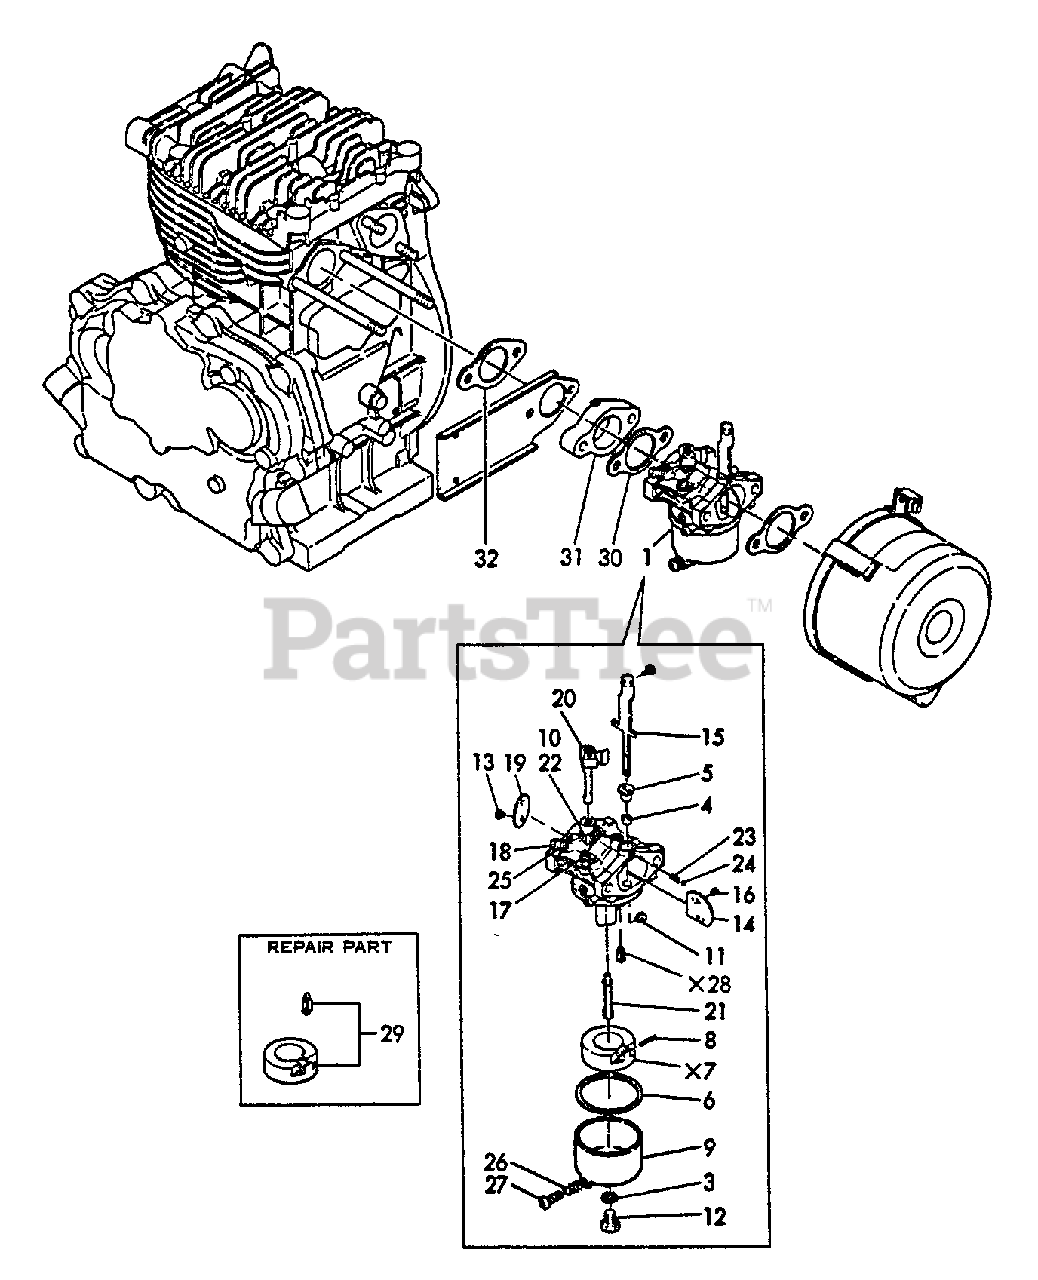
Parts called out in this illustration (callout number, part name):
1	CARBURETOR
3	WASHER
4	RING, CHOKE SHAFT
5	RING, CHOKE LEVER
6	GASKET, FLOAT CHAMBER
7	FLOAT
8	PIN
9	BODY
11	JET, MAIN
12	BOLT
13	SCREW
14	VALVE, CHOKE
15	CARBURETOR
17	JET, PILOT
18	SCREW
19	VALVE, THROTTLE
20	SHAFT, THROTTLE
21	NOZZLE, MAIN
22	SCREW
23	SPRING, CHOKE
24	BALL, CHOKE
27	SCREW
29	NEEDLE ASSY - RUBBER
30	GASKET, INTAKE
31	INSULATOR
32	GASKET, INTAKE
